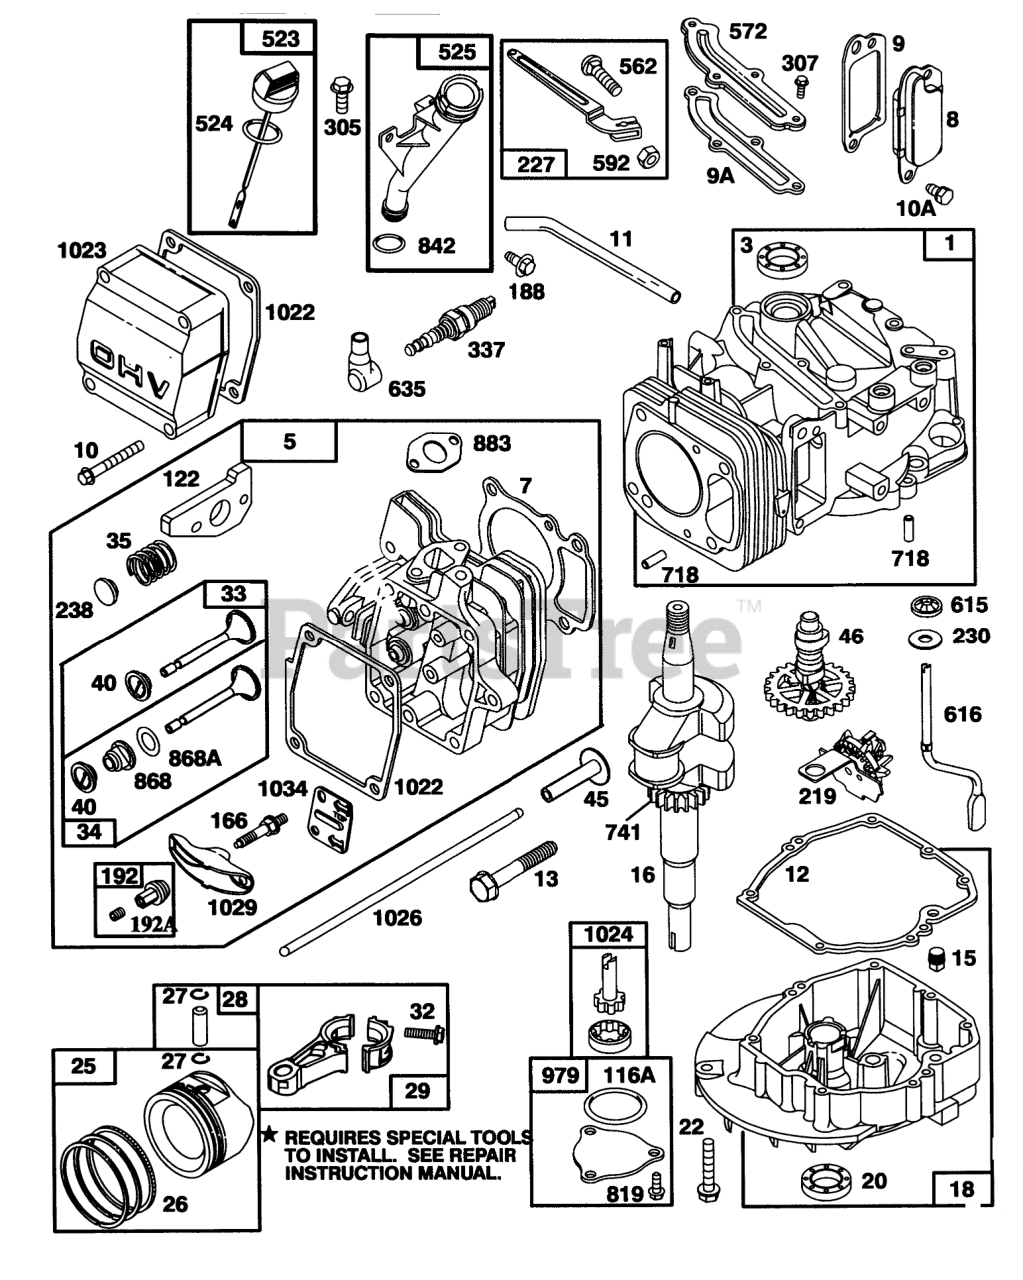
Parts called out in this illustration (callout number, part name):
1	CYLINDER ASSEMBLY
3	SEAL - OIL
5	CYLINDER HEAD
7	CYLINDER HEAD GASKET
8	Breather Assy
9	BREATHER GASKET
9A	GASKET-BREATHER
10	HEX HEAD SCREW
10A	HEX HEAD SCREW
11	TUBE - BREATHER
12	ENGINE BASE GASKET
13	CYLINDER HEAD SCREW
15	PIPE PLUG
16	CRANKSHAFT
18	ENGINE SUMP
20	SEAL-OIL
22	SCREW - ENGINE BASE
25	STD PISTON ASSEMBLY
26	STD RING SET
27	PISTON PIN LOCK
28	PIN ASM - PISTON
29	CONNECTING ROD
32	Connecting Rod
33	EXHAUST VALVE
34	INTAKE VALVE
35	VALVE SPRING
40	SPRING RETAINER
45	VALVE TAPPET
46	CAM GEAR
116A	O RING SEAL
122	ADAPTER ASSEMBLY
166	ROCKER ARM STUD
188	Screw-Cap
192	NUT - HEX SPECIAL
192A	SCREW SET
219	GOVERNOR/OIL SLINGER
227	GOVERNOR LEVER ASSEMBLY
230	WASHER
238	VALVE CAP
305	SCREW - HEX HEAD
307	SCREW - SEM
337	PLUG-SPARK
358	GASKET SET
523	DIPSTICK-OIL
524	O-RING
525	OIL FILLER TUBE
562	GOVERNOR LEVER BOLT
572	BAFFLE - CYCLINDER
592	HEX NUT
615	FASTENER
616	GOVERNOR CRANK
635	SPARK PLUG ELBOW
718	DOWEL - SLEEVE
741	TIMING GEAR
819	SCREW - SEM
842	O-RING
868	SealAssy-Valve
868A	Seal-Valve
883	EXHAUST GASKET
979	OIL PUMP COVER
1022	ROCKER COVER GASKET
1023	COVER - VALVE
1024	OIL PUMP
1026	PUSH ROD
1029	ROCKER ARM
1034	PUSH ROD GUIDE
